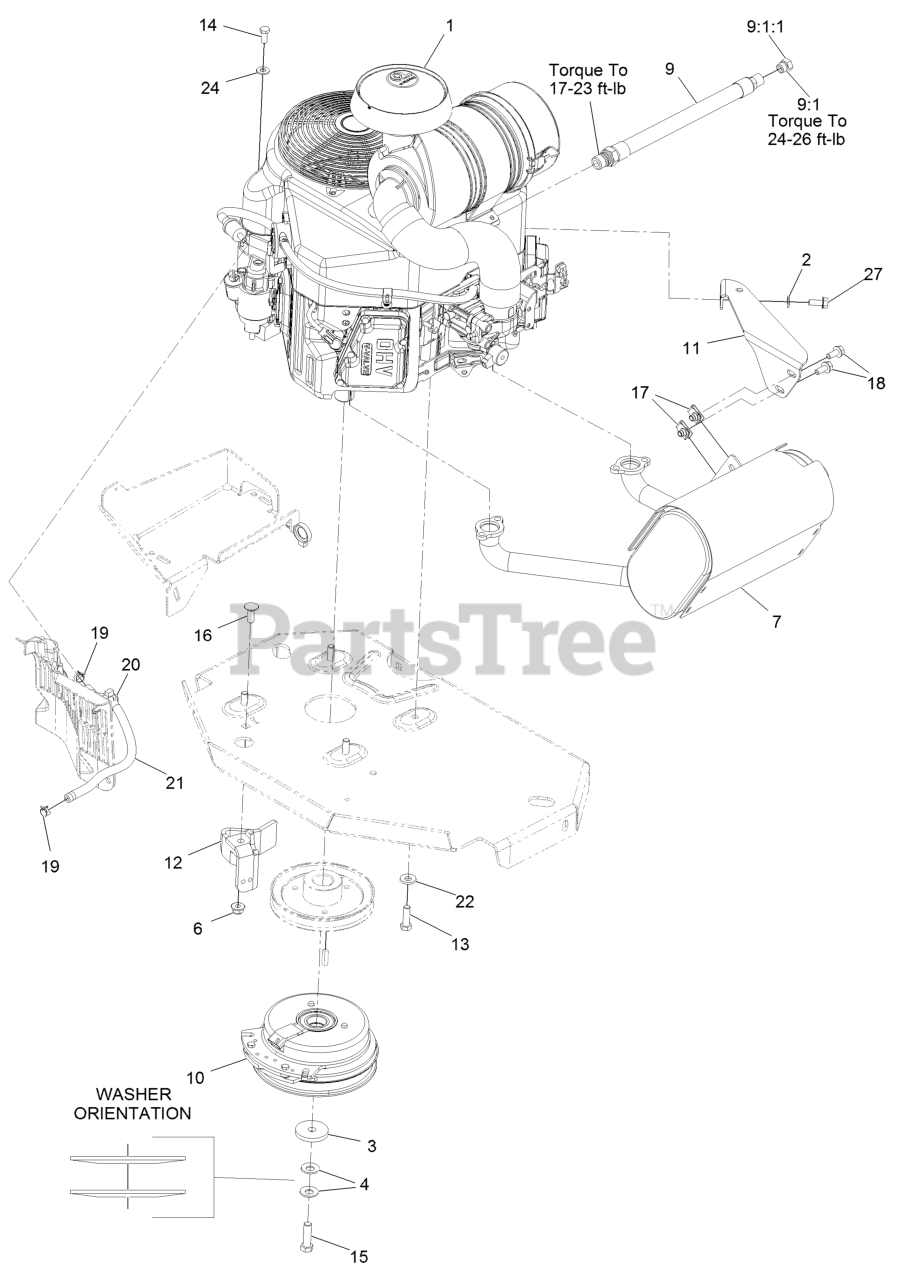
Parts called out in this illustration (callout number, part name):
2	WASHER-SPRING
3	WASHER-CLUTCH
4	WASHER-SPRING
6	NUT-HF, NI
7	MUFFLER
9	ENGINE OIL DRAIN HOSE ASM
9:1	PLUG-HH
9:1:1	O-RING
10	CLUTCH KIT
11	BRACKET-MUFFLER
12	CLUTCH-ANCHOR
13	SCREW-HH
14	SCREW-HH
15	SCREW-HH 7/16-20 X 1 1/2 W/LOCTITE
16	SCREW-CARR
18	SCREW-HHF
19	CLAMP-HOSE
20	CLAMP-HOSE
21	HOSE-FUEL
22	WASHER-BELLEVILLE
24	WASHER-PLAIN
27	SCREW-HHF
